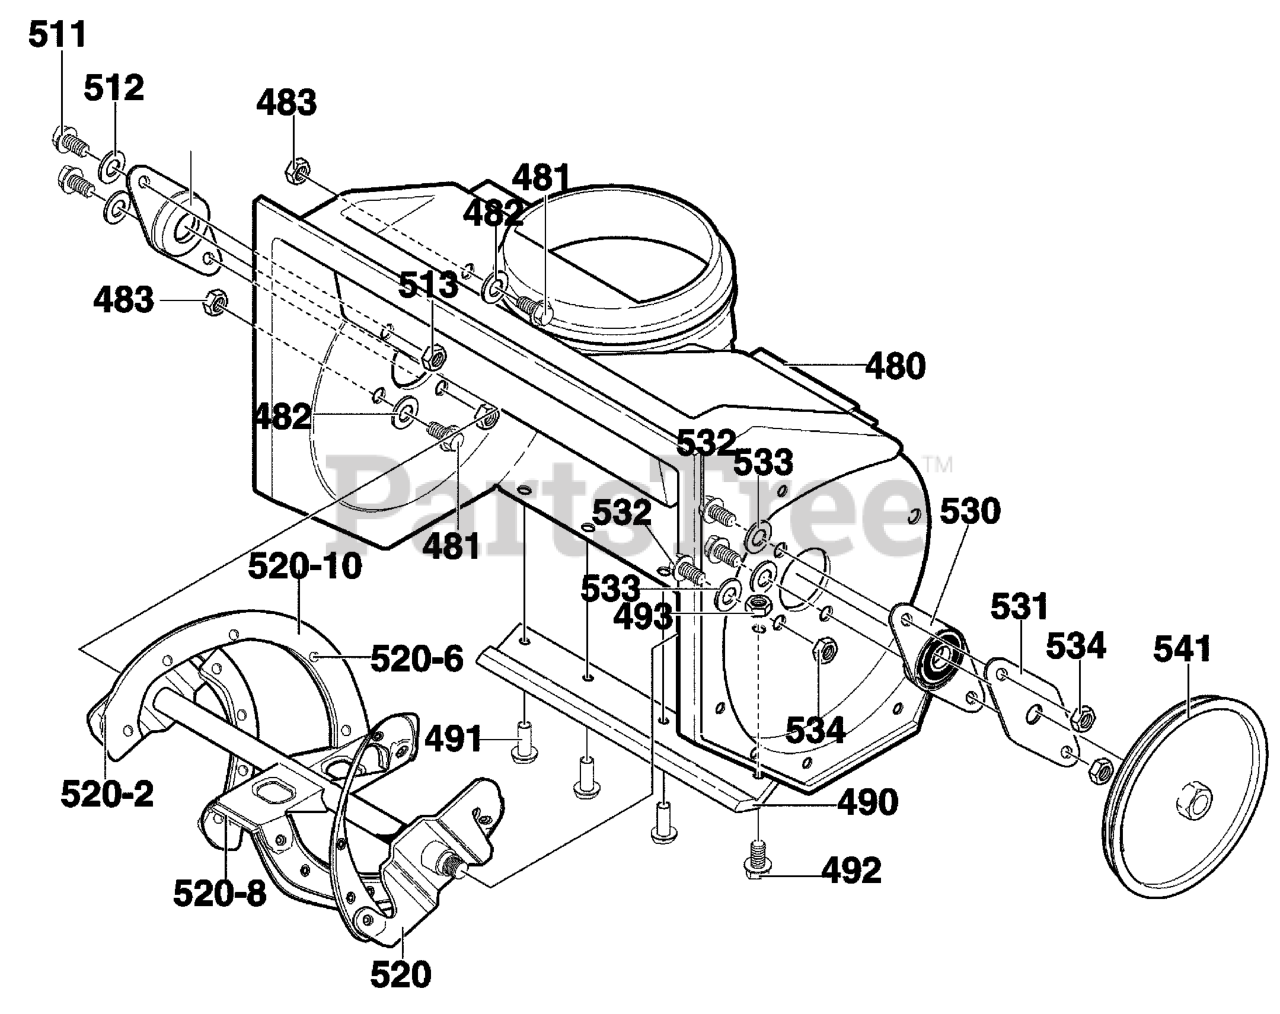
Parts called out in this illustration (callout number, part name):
480	HOUSING, ASSY
481	SCREW, 1/4-20X.75
482	WASHER, FLAT .281X.63X.065
483	NUT, 1/4-20
490	BLADE, SCRAPER
491	RIVET, OVSET
492	SCREW, 1/4-20X.75
493	NUT, 1/4-20
510	BRNG,FL
511	SCREW, 1/4-20X1.00
512	WASHER, FLAT .281X.63X.065
513	NUT, 1/4-20
520	AUGER, ASSY
520-2	BLADE, AUGER
520-6	RIVET
520-8	BLADE, CENTER
520-10	AUGER & BLADE SUPPORT
530	BEARING & PLATE ASSY.
531	PLATE, RETAINER
532	SCREW, 1/4-20X.63
533	WASHER, FLAT .281X.63X.065
534	NUT, 1/4-20
